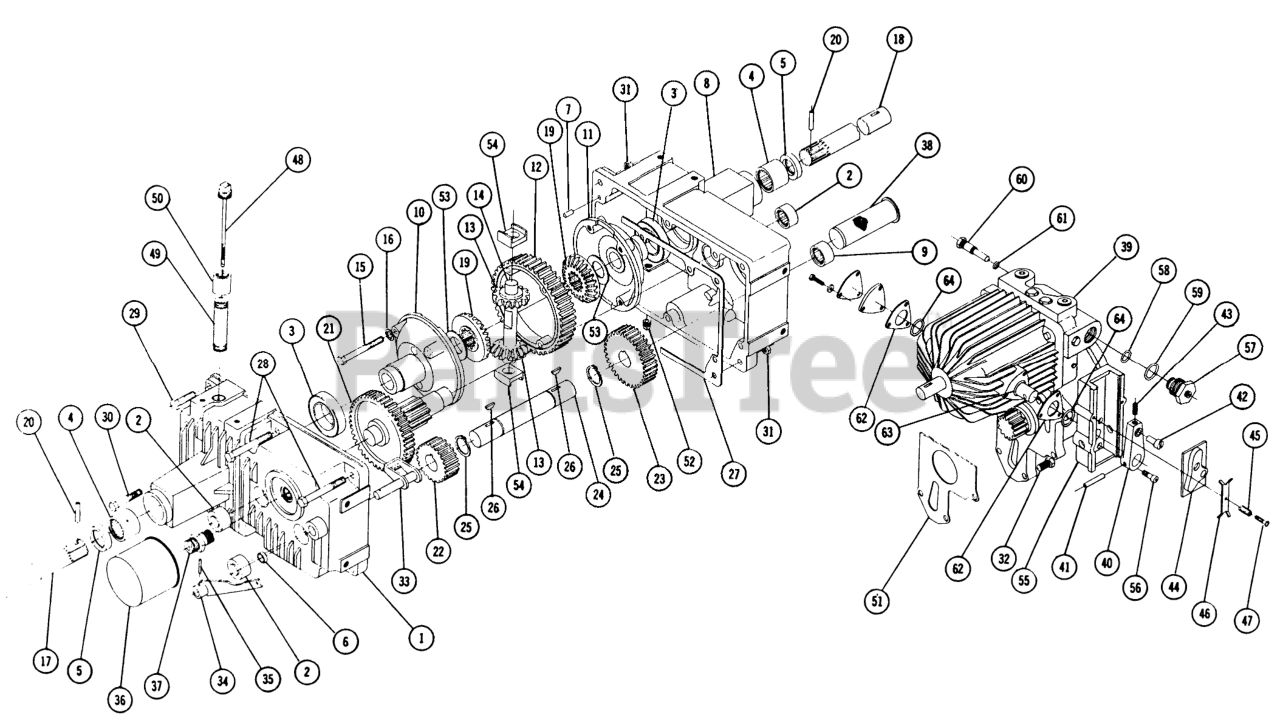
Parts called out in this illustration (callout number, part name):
2	BEARING-NEEDLE
5	SEAL-OIL
7	PIN-DOWEL
10	DIFF CASE RH
12	GEAR DIFF BULL
26	Key
28	Bolt Hex 3/8-16 x 5
29	Bolt, 3/8 16 x 2
30	Bolt Hex 3/8-16 x 1
32	Bolt, 3/8-16 x 1
37	FITTING
39	SRV BULLT 437B
40	Arm-Cam Follower
41	ROLL PIN 1/4 X 1-1/4
43	Set Screw-1/4-20 x 1/2
44	CAM
45	SPRING CAM
47	Screw Round Head #8-32 x 7/8
49	Nipple 1/2 Pipe x 31/2
50	Coupling 1/2 Pipe
54	BLOCK
59	"O" Ring 7/8 x 11/16 x 3/32
63	"O" Ring
